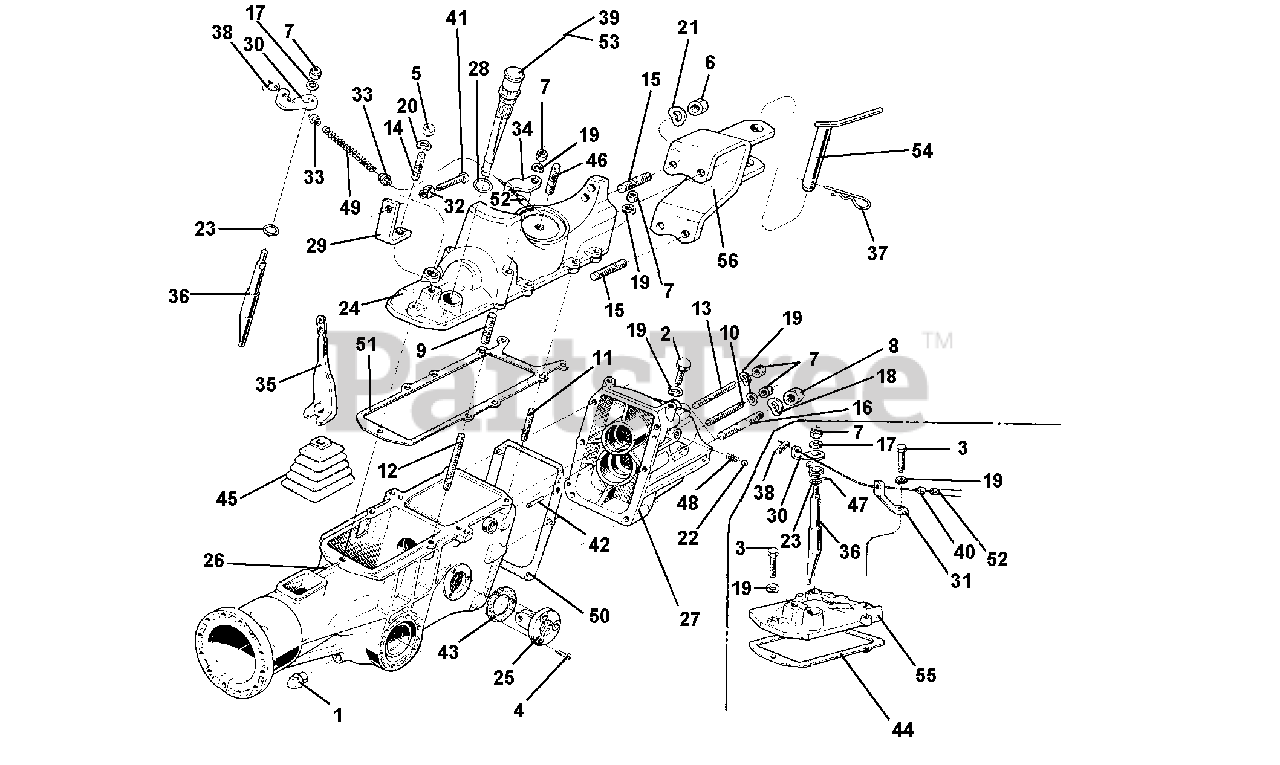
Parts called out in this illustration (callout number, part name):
1	PLUG 1/4 GAS
2	SCREW M8 X 25
3	SCREW TE M8 X 30
4	SCREW M6 X 16
7	NUT, SELF LOCKING M8
9	STUD M8 X 46 X 20 X 12
10	STUD M8 X 58 X 16 X 16
11	STUD M8 X 40 X 14 X 14
13	STUD M8 X70 X 16 X 16 8G
14	STUD M10 X 37 X 19 X 15 8G
17	WASHER, FLAT 8.4
18	SUPER WASHER 12 DIN 6796
19	WASHER, LOCK 8.4
20	WASHER, LOCK 10.5
21	WASHER, LOCK 13
22	BALL 15/32 RIV RB-11.906
23	O-RING 2056 14.00 X 1.78
24	SYNCHRONIZED PTO COVER 745
25	FLANGE, REVERSE SPEED
26	GEARBOX 745 / 606-605
28	RUBBER RING
29	BRACKET CLUTCH CONTRAST
30	LEVER RELEASE
31	CONTRAST DIFFERENTIAL SHEATH
32	STOP RING NUT
35	CLUTCH LEVER
38	CLAMP, CABLE
39	CAP, WITH MEASURING ROD
40	END, SHEATH
41	SCREW ADJUSTING M8
42	PARALLEL PIN D 6 X 20
44	GASKET, COVER
46	DRILLED PIN
48	P.T.O. SPRING
50	COVER GASKET
51	COVER GASKET
52	SHEATH CABLE
53	CAP WITH MEASURING ROD
55	COVER DIFFERENTIAL
56	TOW COUPLING
